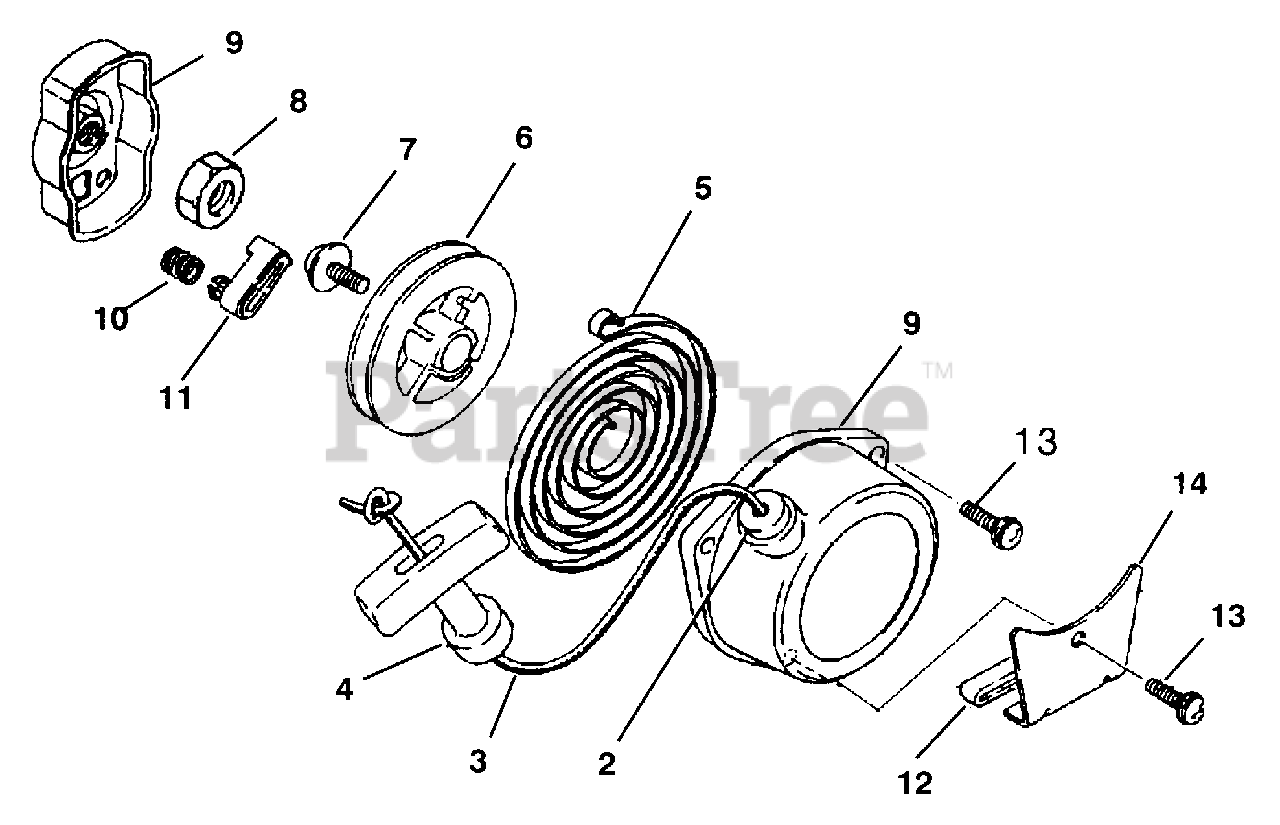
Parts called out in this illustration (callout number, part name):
1	STARTER ASSY
3	ROPE, STARTER
4	KNOB, STARTER
5	SPRING, REWIND
7	SCREW & WASHER
8	NUT
9	PULLEY ASSY, STARTER
10	SPRING, RETURN
11	RATCHET
13	SCREW & WASHER
14	BRACKET
